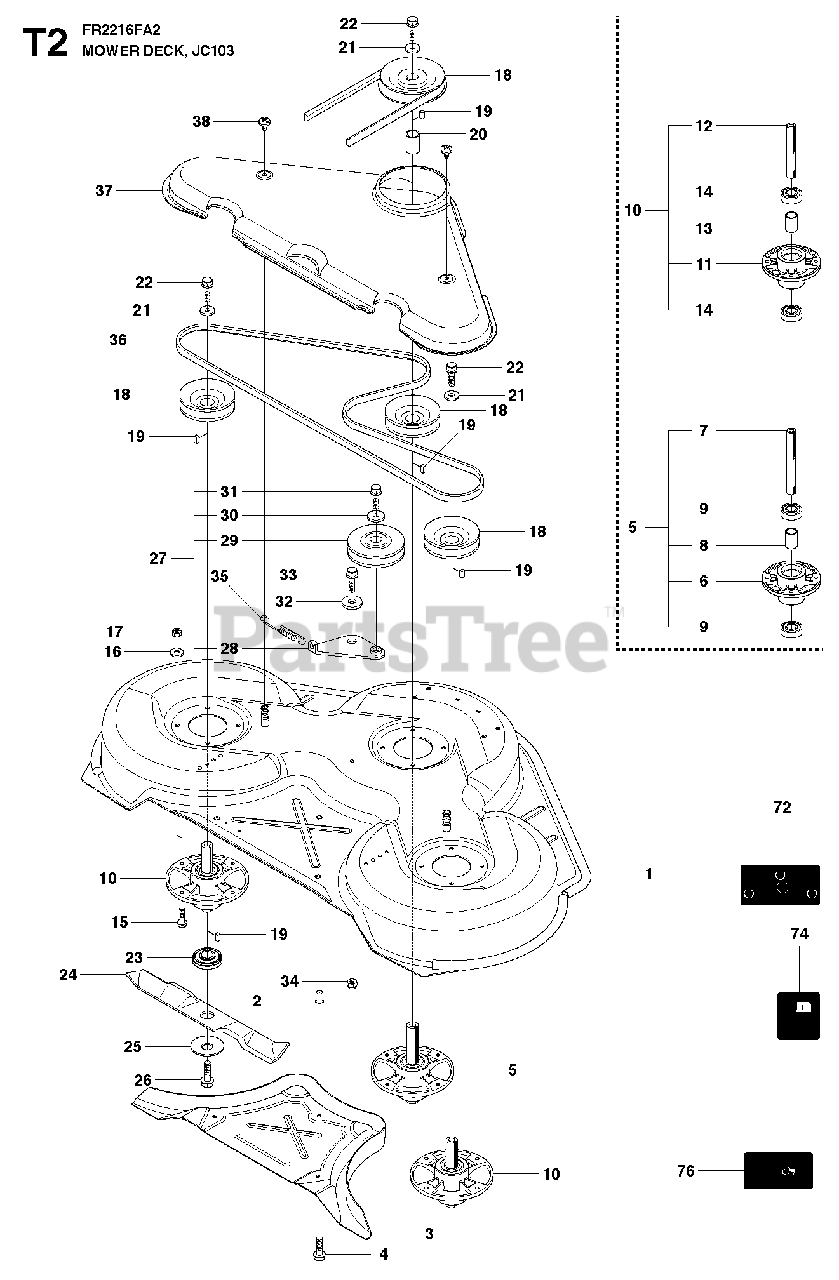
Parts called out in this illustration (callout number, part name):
5	RP SPINDLE ASSY
6	BEARING HOUSING
7	SHAFT
8	SPACER
9	BEARING
10	RP SPINDLE ASSY
11	BEARING HOUSING
12	AXLE
13	SPACER
14	BEARING
16	WASHER BRB 8.4X17
17	LOCKNUT M8
24	BLADE
27	BELT TENSIONER ASSY
28	BELT TENSIONING ARM
29	PULLEY
30	SPACER
31	BOLT
32	WASHER
34	LOCKNUT M8
36	BELT
